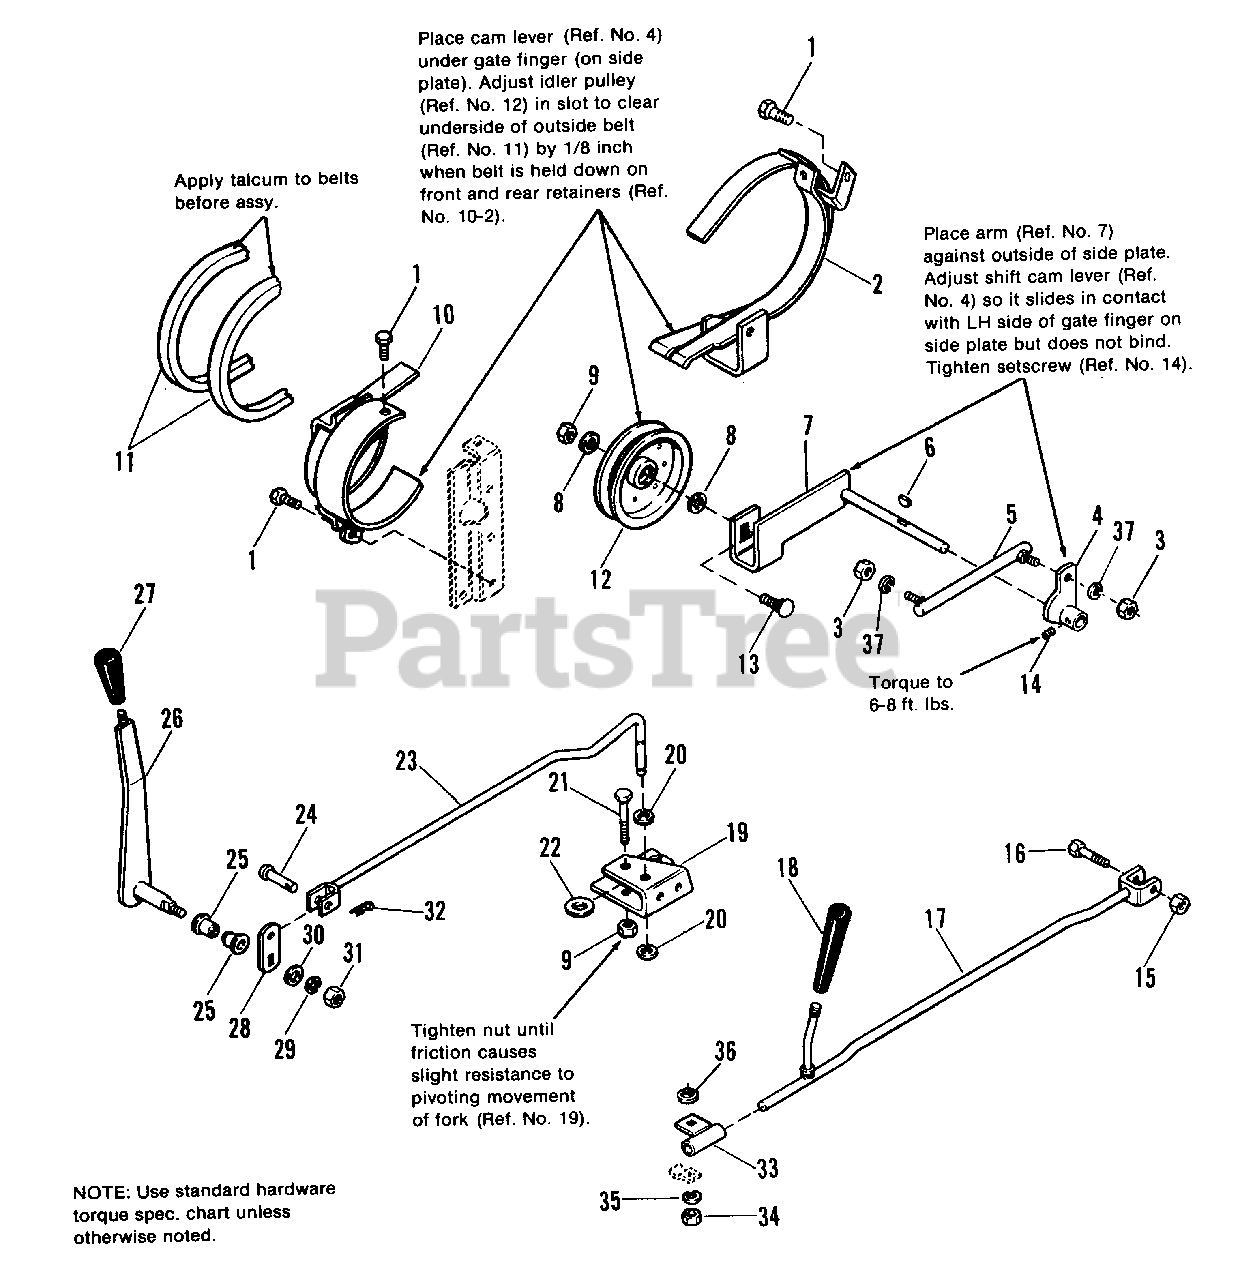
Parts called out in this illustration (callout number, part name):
1	SCREW, Hex Hd., Taptite, 5/16-18 x 1/2
2	RETAINER ASSY., Rear
3	NUT, Hex, Full, 5/16-24
4	LEVER ASSY., Cam Shaft
5	JOINT, Ball
6	KEY, Woodruff, #5
7	ARM ASSY., Idler
8	WASHER, Plain, 5/16
9	LOCKNUT, Hex, 3/8-16
10	RETAINER ASSY., Belt
11	V-BELT, Drive
12	PULLEY, Idler
13	BOLT, Rd. Hd., 3/8-16 x 1-1/4
14	SETSCREW, 1/4-20 x 1/4
15	LOCKNUT, Hex, 5/16-18
16	CAPSCREW, Hex Hd., 5/16-18 x 1-1/2
17	ROD ASSY., Shift
18	HANDLE, Shift Rod
19	FORK, Shift
21	CAPSCREW, Hex Hd., 3/8-16 x 2
23	ROD ASSY., Control
26	LEVER ASSY., Control
27	KNOB
29	LOCKWASHER, 3/8
30	WASHER, Plain, 3/8
31	NUT, Hex, Full, 3/8-16
32	PIN, Cotter, 3/32 x 3/4
33	GUIDE ASSY., Shift Rod
34	NUT, Hex, Full, 1/4-20
35	LOCKWASHER, 1/4
36	WASHER, Plain, 3/8
37	LOCKWASHER, 5/16
